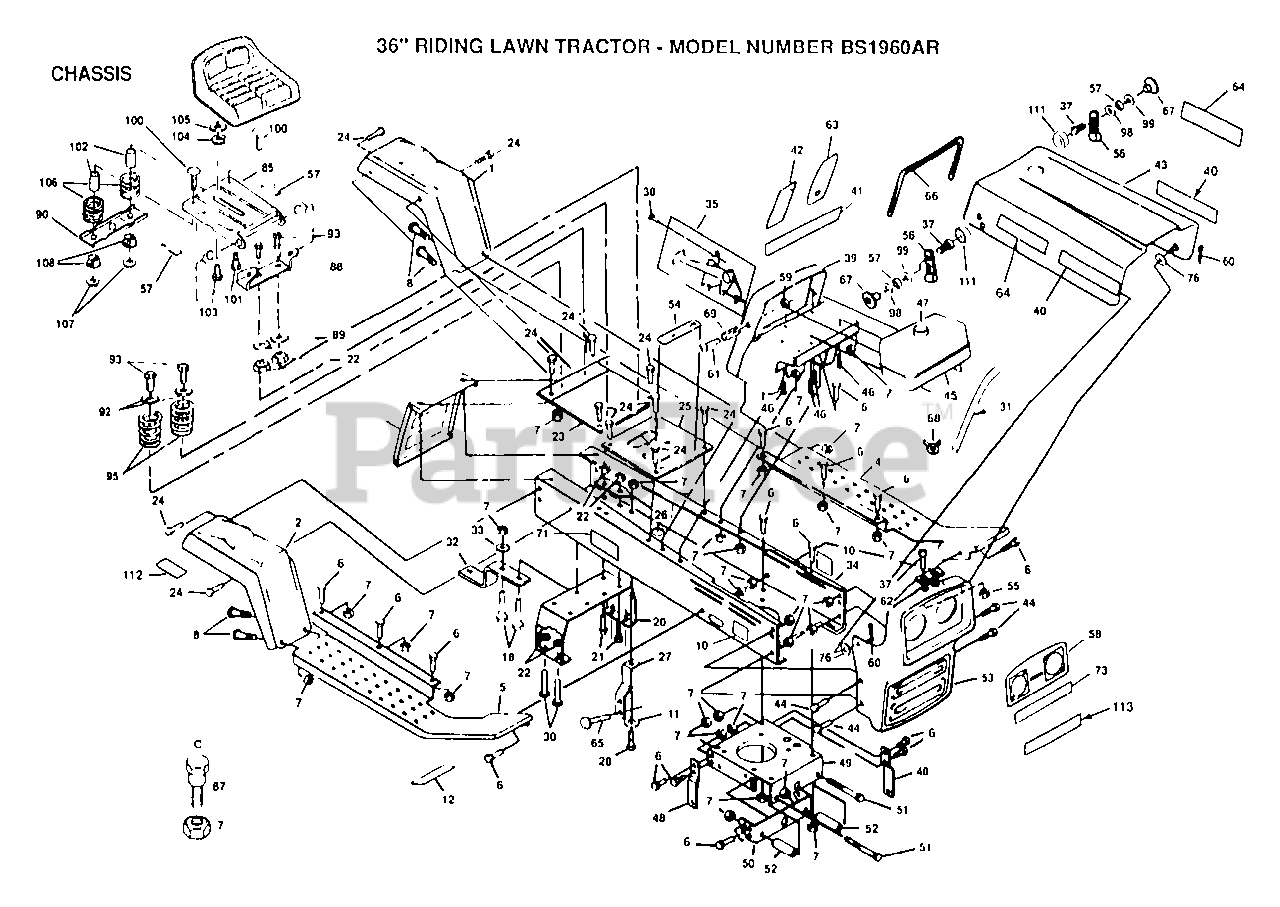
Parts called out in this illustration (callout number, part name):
3	REAR COVER T
6	BOLT
8	BOLT
11	WASHER
18	BOLT
21	BOLT
24	SCREW LT
25	CHASSIS CVR W/S
27	AXLE LT
30	BOLT
37	SCREW
45	TANK.FUEL.LT
48	BRAKE ROD BRA T
49	ENGINE BASE
50	ROCKER BAR SUPP
52	ROCKER PIVOT LT
56	HOOD LATCH T
57	STRIP FORM
58	DECAL HEADLIGHT
61	SCREW
62	HOOD BUMPER
65	SCREW
67	WELDNUT
69	SPACER LT
76	WASHER M
90	BRKT SWITCH
92	WASHER
93	SCREW GTV
99	WASHER LT
100	BOLT
102	SPACER SPLIT
103	BOLT
104	LOCKWASHER
105	WASHER
106	SPRING
107	NUT T
108	BUSHING
111	SNAP CAP LT
